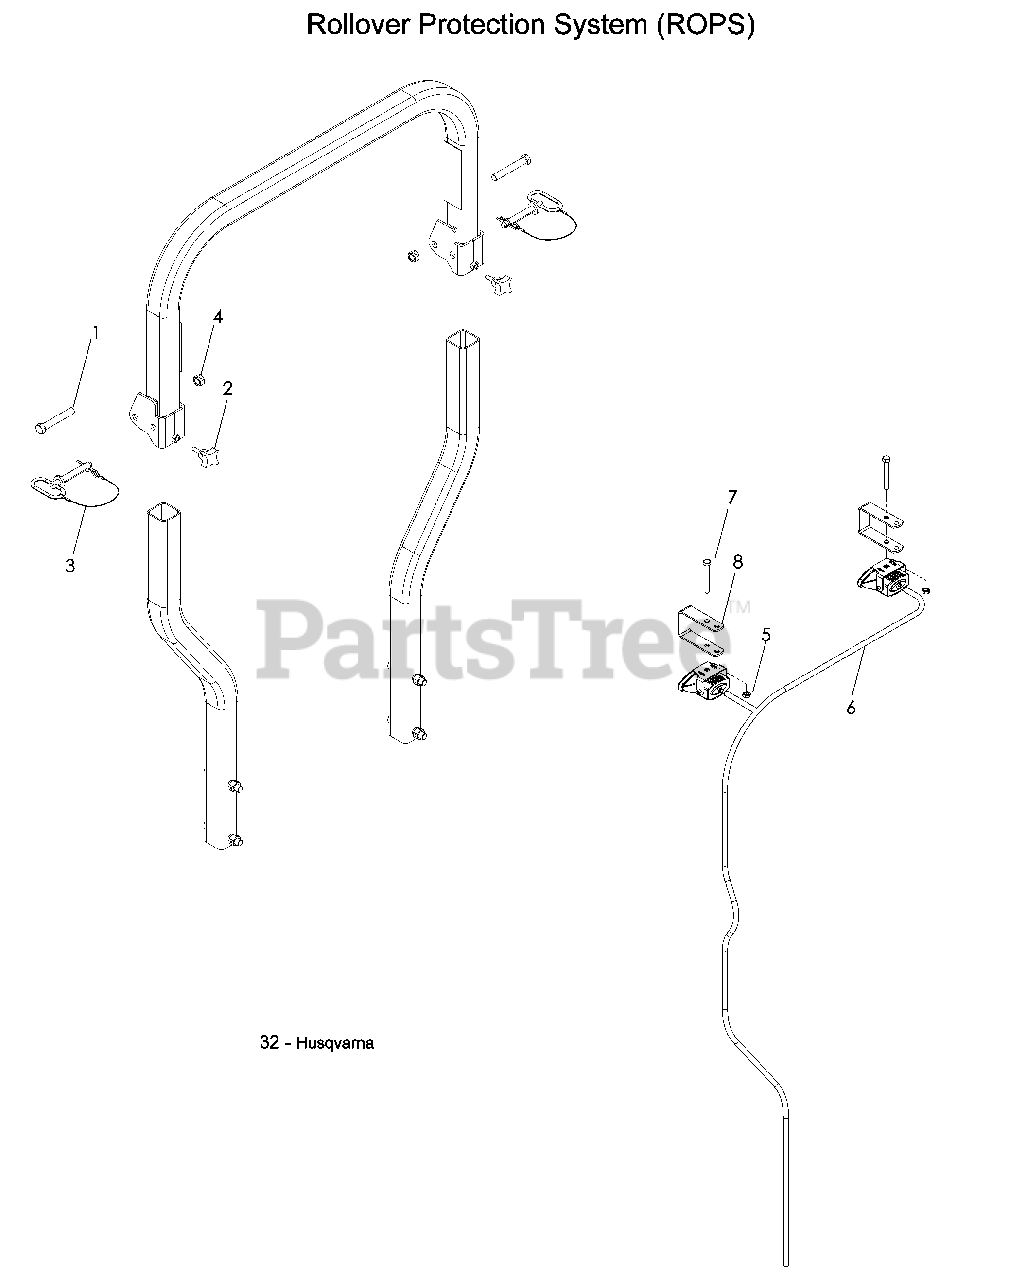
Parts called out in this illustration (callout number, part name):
1	HCS ½-13 x 3¼
2	KNOB w/ STUD
3	LANYARD w/PIN ½"
4	NUT ½-13 CNTRLK
5	NUT 5/16-18 JAM
6	LIGHT HARNESS
7	HCS 5/16-18 x 2½
8	BRACKET, MOUNTING
